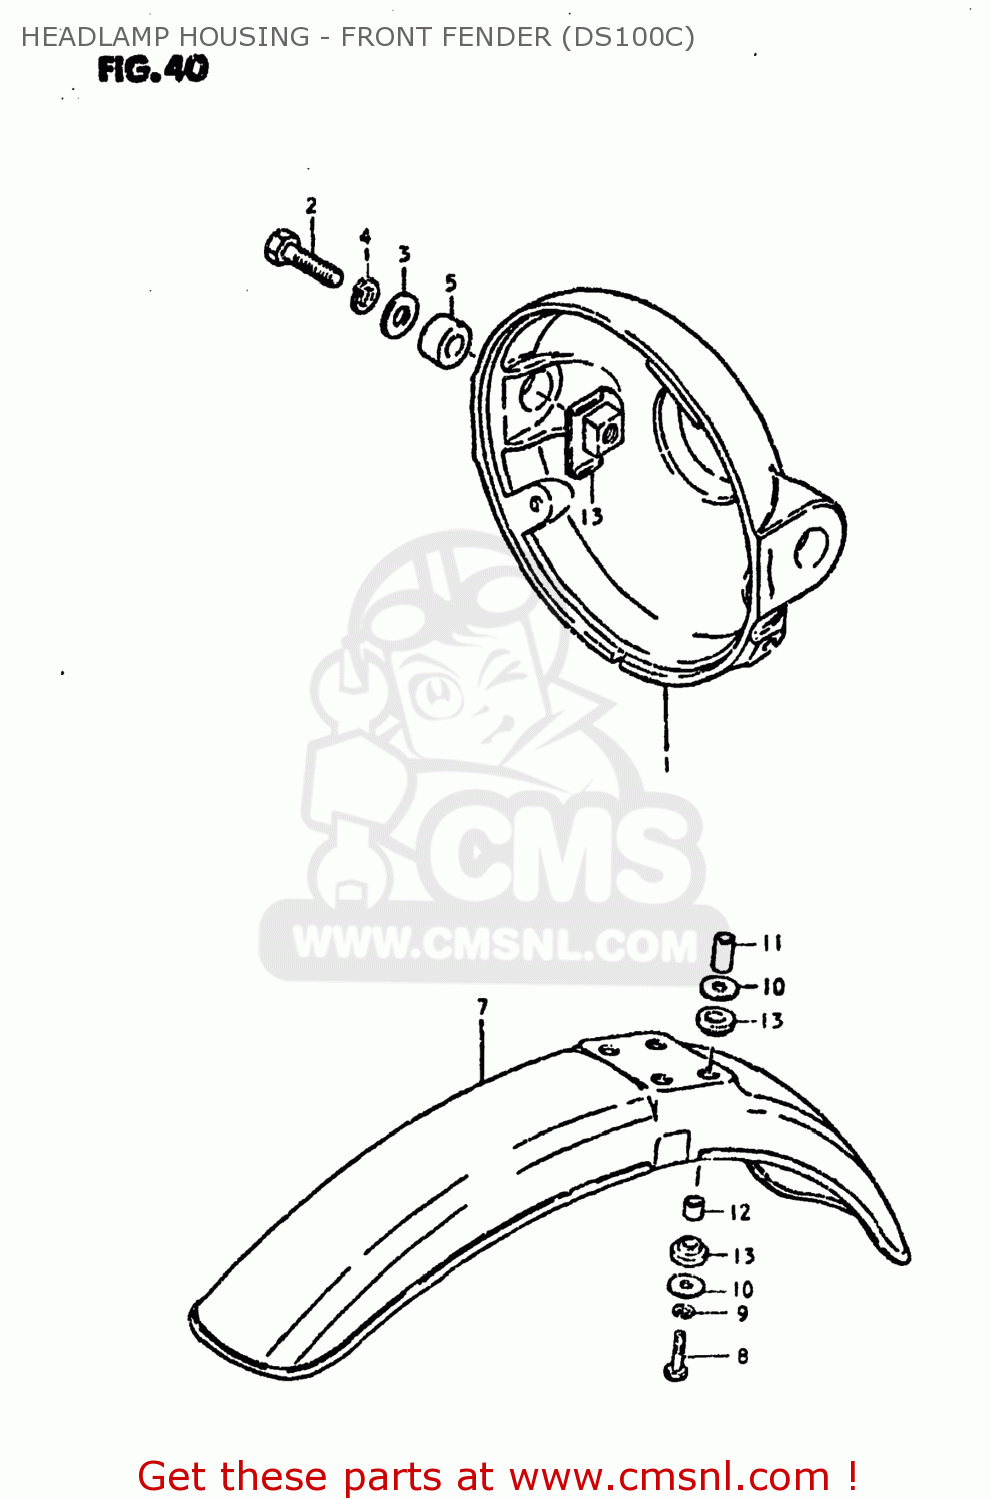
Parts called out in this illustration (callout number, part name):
1	HOUSING,HEADLAMP
2	BOLT
3	WASHER
4	LOCK WASHER
5	SPACER (8.8X12X7)
6	PLATE,HEADLAMP HOUSING
7	FENDER,FRONT
8	BOLT 6X40
9	LOCK WASHER
10	WASHER (6.5X24X1.2)
11	SPACER
12	SPACER (6.5X10.5X13.5)
13	CUSHION
